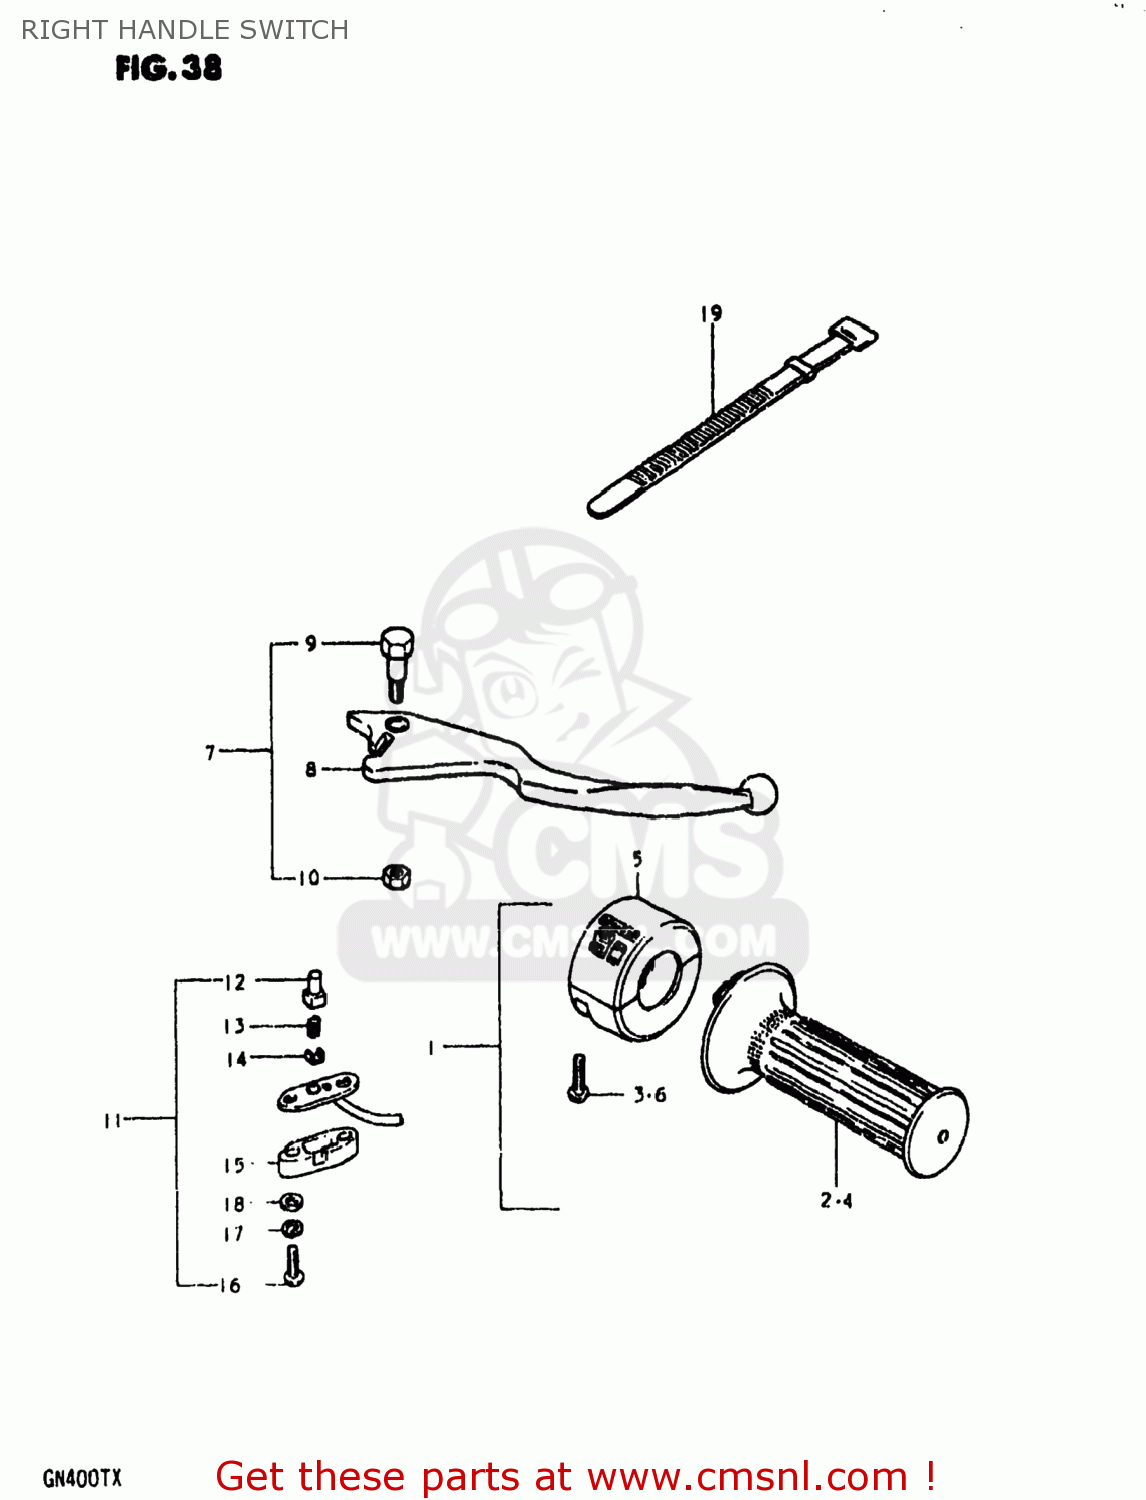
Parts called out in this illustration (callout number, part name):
1	CASE ASSEMBLY,THROTTLE
2	GRIP,THROTTLE
3	SCREW
4	GRIP,THROTTLE
5	CASE ASSY,THROTTLE
6	SCREW
7	LEVER ASSEMBLY,BRAKE
8	LEVER,BRAKE
9	BOLT
10	NUT 6MM
11	SWITCH ASSEMBLY
12	HOLDER
13	SPRING
14	PLATE
15	COVER,FR BK TERMINAL BASE
16	SCREW
17	LOCK WASHER
18	WASHER
19	CLAMP(L:120)
